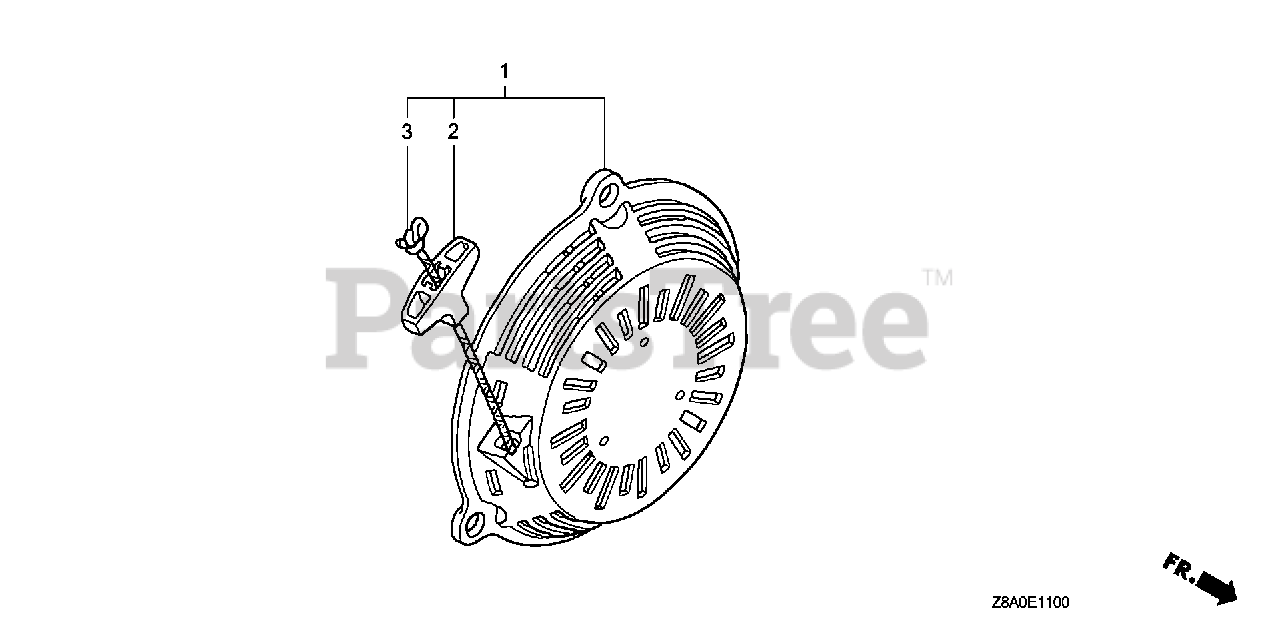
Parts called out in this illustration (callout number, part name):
1	STARTER ASSY., RECOIL *NH1* (BLACK)
1	STARTER ASSY., RECOIL *NH1* (SHORT ROPE) (BLACK)
2	KNOB, RECOIL STARTER
3	ROPE, RECOIL STARTER (#3.5X52")
